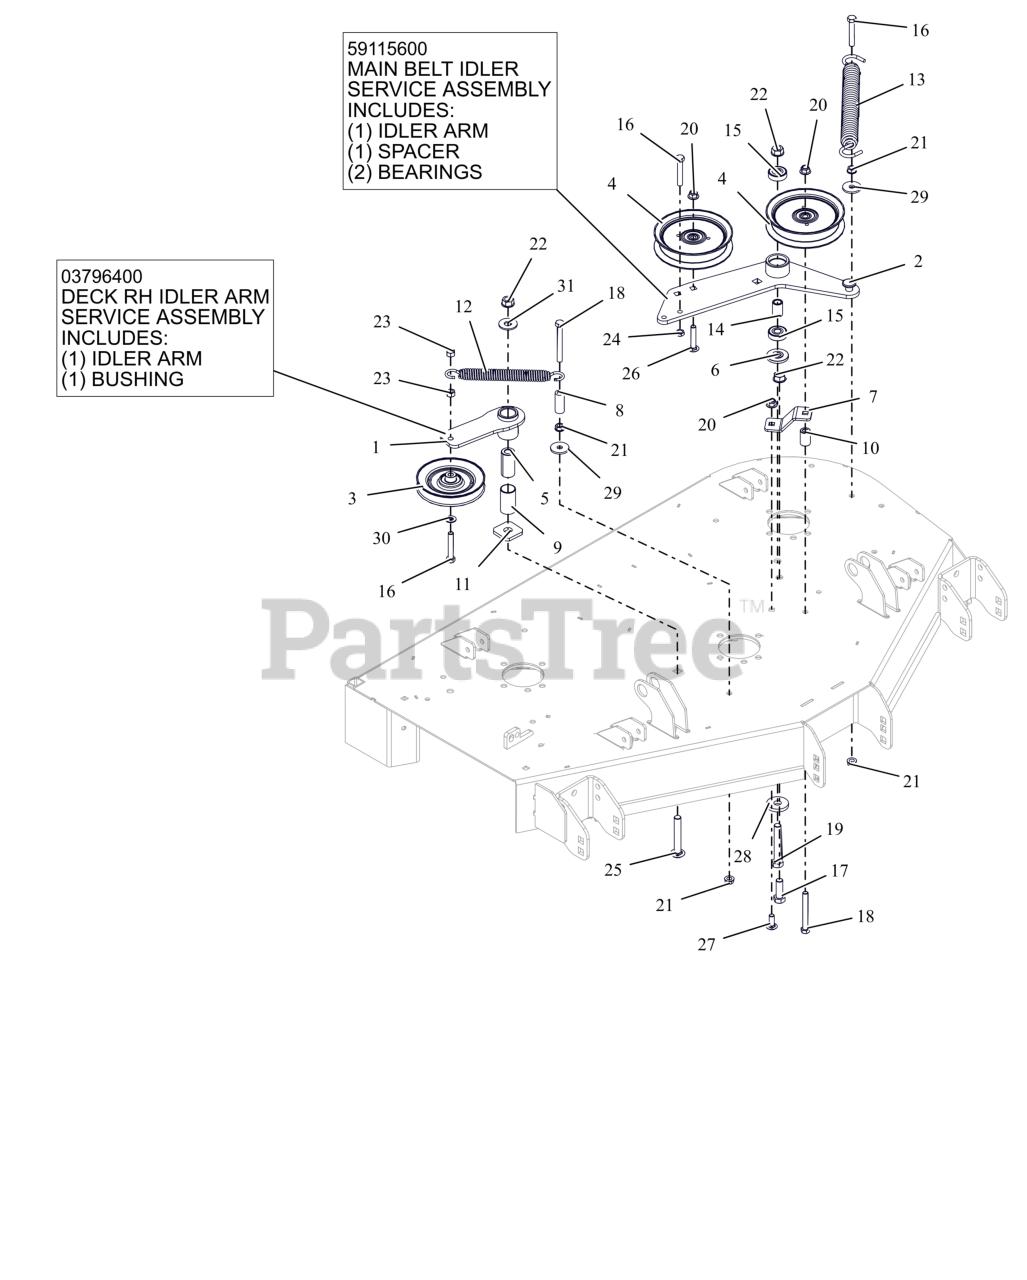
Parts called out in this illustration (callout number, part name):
1	WMT, IDLER ARM - BLACK
1	ASM, IDLER ARM (DECK)
2	WLDMT, DECK PTO IDLR ARM
2	ASSEMBLY, MAIN BELT IDLER
3	IDLER, V-5.00"
4	IDLER, FLAT 5.00"
5	BSHG, SPCR .502X.997X2.03 PM
6	SPACER, IDLER ARM
7	PTO FIXED IDLER MTG BRKT -RED
8	HOSE, .38 X 1.65
9	BSHG, 1.00X1.125X1.937
10	BUSHING, SLV .380X.750X1.190
11	WSHR-FLT .640X1.75X.250
12	SPRING, EXTENSION
13	SPRING, EXTENSION
14	SPACER .510 X .75 X 1.1485
15	BRG-BALL .500X1.38X.437
16	BLT,HEX .38-16X2.25 G5 ZCC
17	BLT,HEX .50-13X1.50 G5 ZCC
18	BLT, HEX .38-16X3.25 G5 ZCC
19	BLT,HEX .50-13X3.25 G5 ZCC
20	NUT,NYL-FLG .38-16 GF ZCC
21	NUT, SPNLK-FLG .38-16 G5 ZCC
22	NUT-LK-CTR-FLG .500-13 GG ZCC
23	NUT-LK-CTR .38-16 ZC120
24	NUT-JAM .375-16 G2 ZCC
25	BTL,RHSSN .500-13 X 3.25 G5 ZCC
26	BLT,RHSSN.375-16X2.00 G5 ZCC
27	BLT,RHSSN .38-16X1.00 G5 ZCC
28	WSHR-FL-STL 0.557X1.625X0.25 ZCC
29	WSHR,FLT .406X1.375X.135 ZCC
30	WSHR,FLT .406X.812X.065 ZCC
31	WSHR,FLT .563X1.375X.109 ZCC
